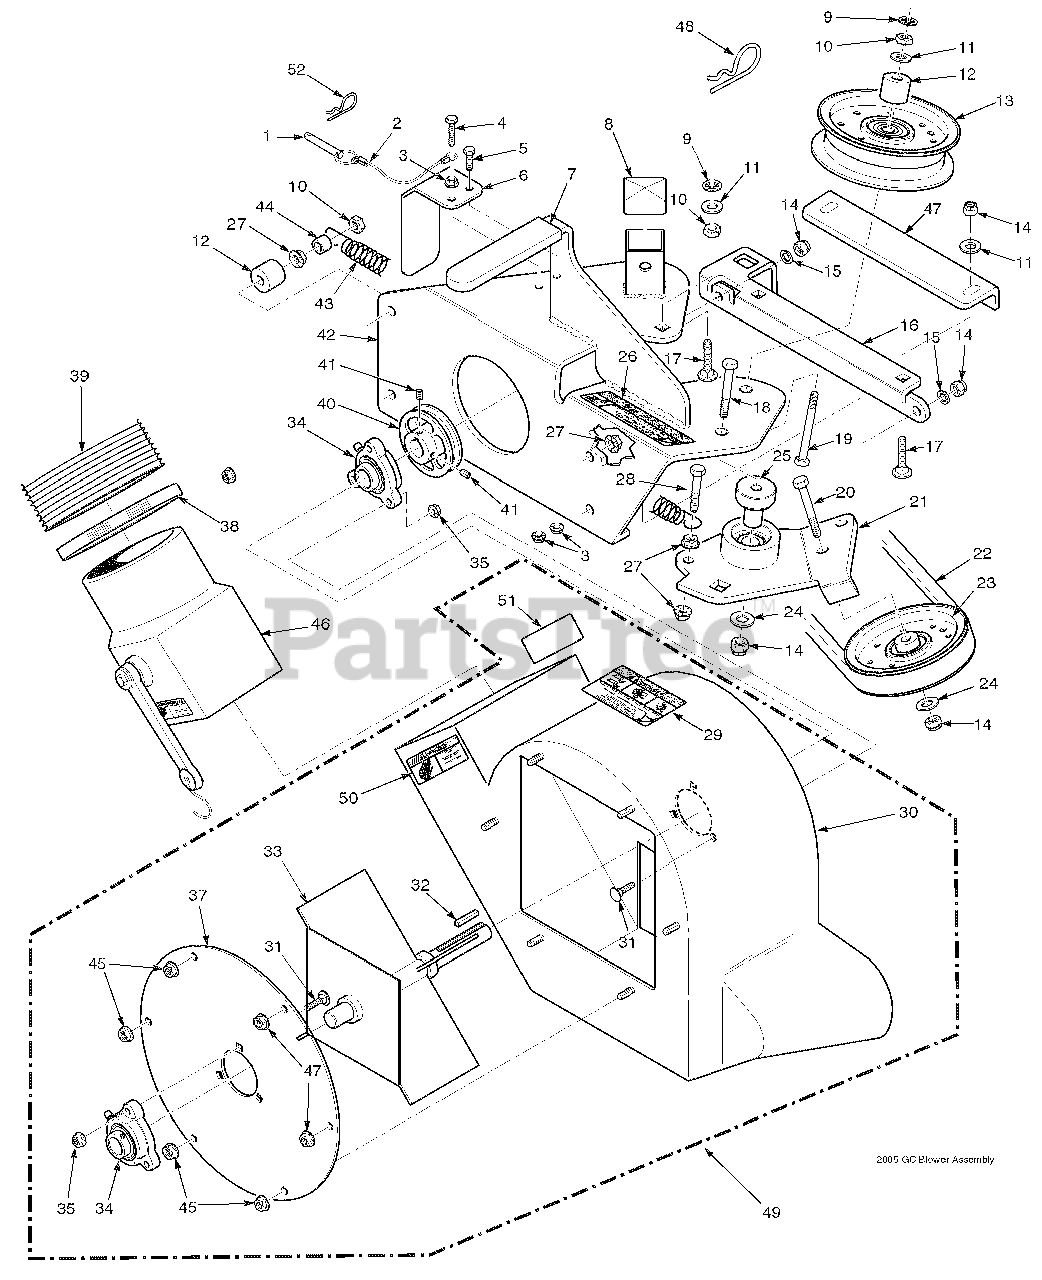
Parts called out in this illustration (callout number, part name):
1	Pin, Ring 2-1/4" Long
2	Lanyard, Deck Height Pin
3	Nut, Serr. Flange 1/4-20
4	Bolt, Hex Head 1/4-20 x 1-1/4"
5	Bolt, Hex Head 1/4-20 x 3/4"
6	Belt Cover, Rear
7	Grip, Blower Lever
8	Cap, Square
9	Nut, Push On 3/8 Thread
10	Lock Nut, 3/8-16
11	Flatwasher, 3/8-.391 x .938 x .105
12	Spacer
13	Pulley, Idler 4" Dia.
14	Nut, Elastic Stop 3/8-16
15	Lockwasher, 3/8-16
16	Plate, Catch Mounting
17	Bolt, Carr. 3/8-16 x 1-1/2"
18	Bolt, Hex Head 3/8-16 x 2-1/4"
19	Bolt, Hex Head 3/8-16 x 3-1/2"
20	Bolt, Hex Head 3/8-16 x 1-3/4"
21	Idler Arm Assembly, GC-STT 61"
22	Belt, GC-STT 61"
23	Pulley, 4" O.D., GC-STT
24	Washer, 3/8 Hardened
25	Pivot, Idler - 61" & 72"
26	Decal, Belt Cover
27	Nut, Serr. Flange 3/8-16
28	Bolt, Hex Head 3/8-16 x 1-1/2 Gr. 8
29	Decal, Danger
30	Blower Housing w/Decals
31	Bolt, Carr. 5/16-18 x 3/4" Gr. 5
32	Key, 1/4 x 1/4 x 1-1/2"
33	Fan Weldment
34	Bearing Assembly
35	Nut, Serr. Flange 5/16-18
36	Flatwasher, 5/16-.344 x .688 x .065
37	Cover, Blower Housing
38	Clamp, 8-5/8" Max Dia.
39	Hose, 8.00" Dia. x 56.00" Long
40	Pulley, 4-3/4" O.D. - 1" Bore
41	Set Screw, 5/16-18 x 3/8"
42	Frame, Blower Mount - 61"
43	Spring, Main Drive
44	Spacer
45	Nut, Serr. Flange 5/16-18
46	Adapter w/Strap
47	Plate, Blower Catch
48	Hair Pin Cotter, .243 x 4"
49	Blower Housing Assembly, GC-STT
50	Decal, Rotating Blower
51	Decal, Blower
